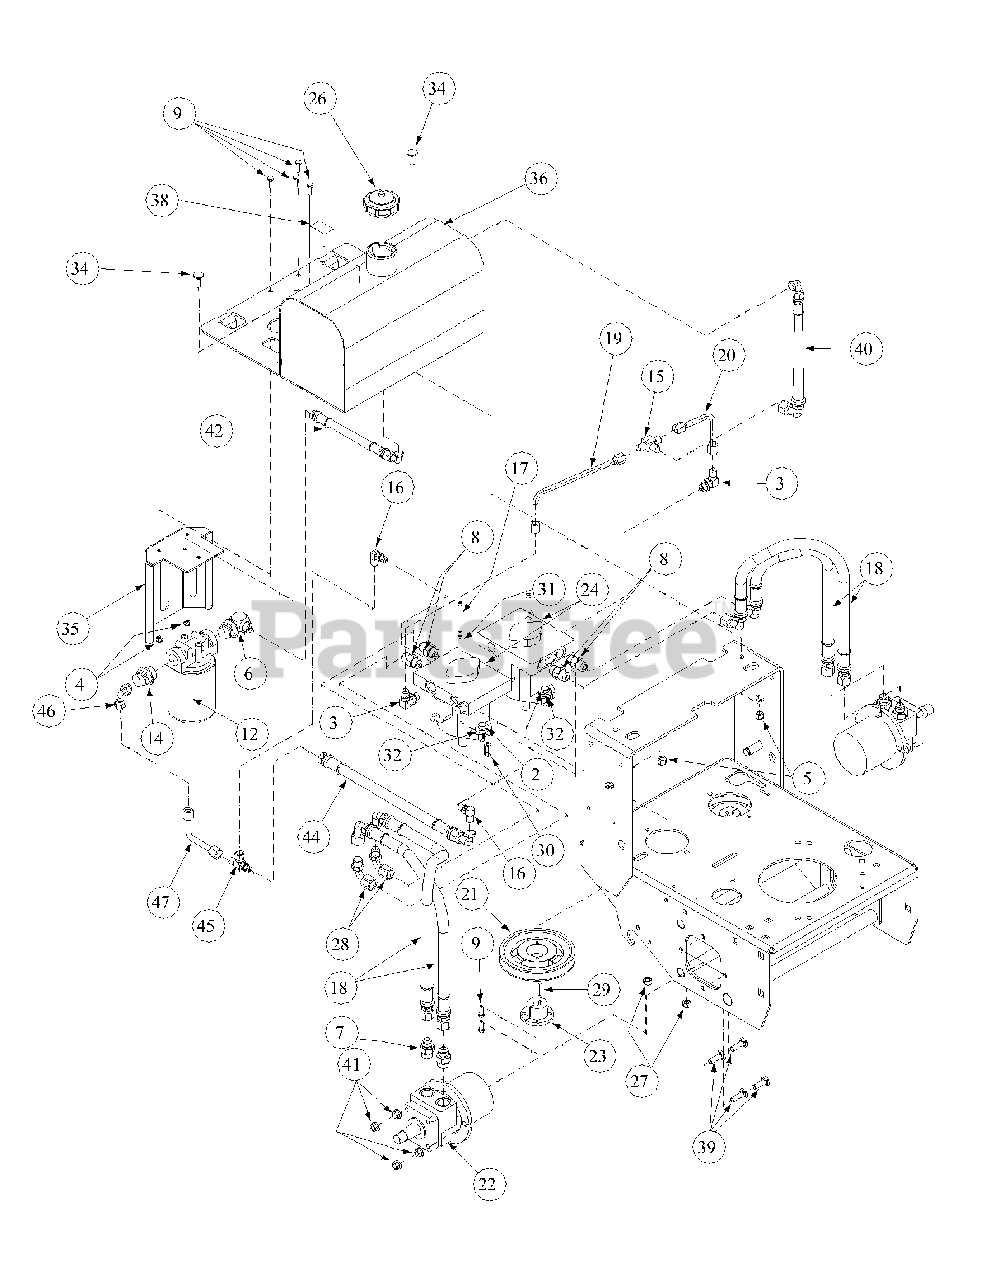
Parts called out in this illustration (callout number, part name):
2	Cap Screw, Standard, 3/8-16 x 1-1/4
3	Fitting, Aeroquip
5	Lock Nut, 3/8-16
6	Elbow 90° 1/2 x 3/4
7	Fitting, Aeroquip
8	Fitting, Aeroquip
9	Cap Screw, 1/4-20 x 3/4
12	Filter Head 3/4
13	Oil Filter
14	Straight Connector 1/2 x 3/4
15	Fitting Aeroquip
16	Fitting, Aeroquip
17	Cap Screw, Socket Head, 1/4-20 x 2-1/2 Zinc
18	Hydro Hose Assembly, Reverse Pressure
19	Hydraulic Line, Pump Return Long
20	Hydraulic Line, Pump Return Short
21	Deck Pulley
22	Hydraulic Motor, Wheel
23	Bushing, 15mm Bore, Split, Type "D"
24	Pump Hydro BDP10L117
26	Cap, Hydraulic Oil Tank
27	Lock Nut, 3/8-16
28	Fitting Aeorquip
30	Nut, Pump Release
31	Spacer, Pump Release
32	Washer, Idler
34	Carriage Bolt, 3/8-16 x 2
36	Fuel Tank Mounting Plate
38	Oil Label, 20W-50
39	Carriage Bolt, 3/8-16 x 1.25
40	Hose Assembly, (00018408 22" +00018440)
41	Hex Nut, Flange Lock, 3/8-16
42	Hose, Filter to Tank
44	Hose Pump to Swing Valve
45	Fitting, Aeroquips
46	Union Hydraulic Flare, 9/16-18
47	Hydraulic Line, Supply Pump Short
